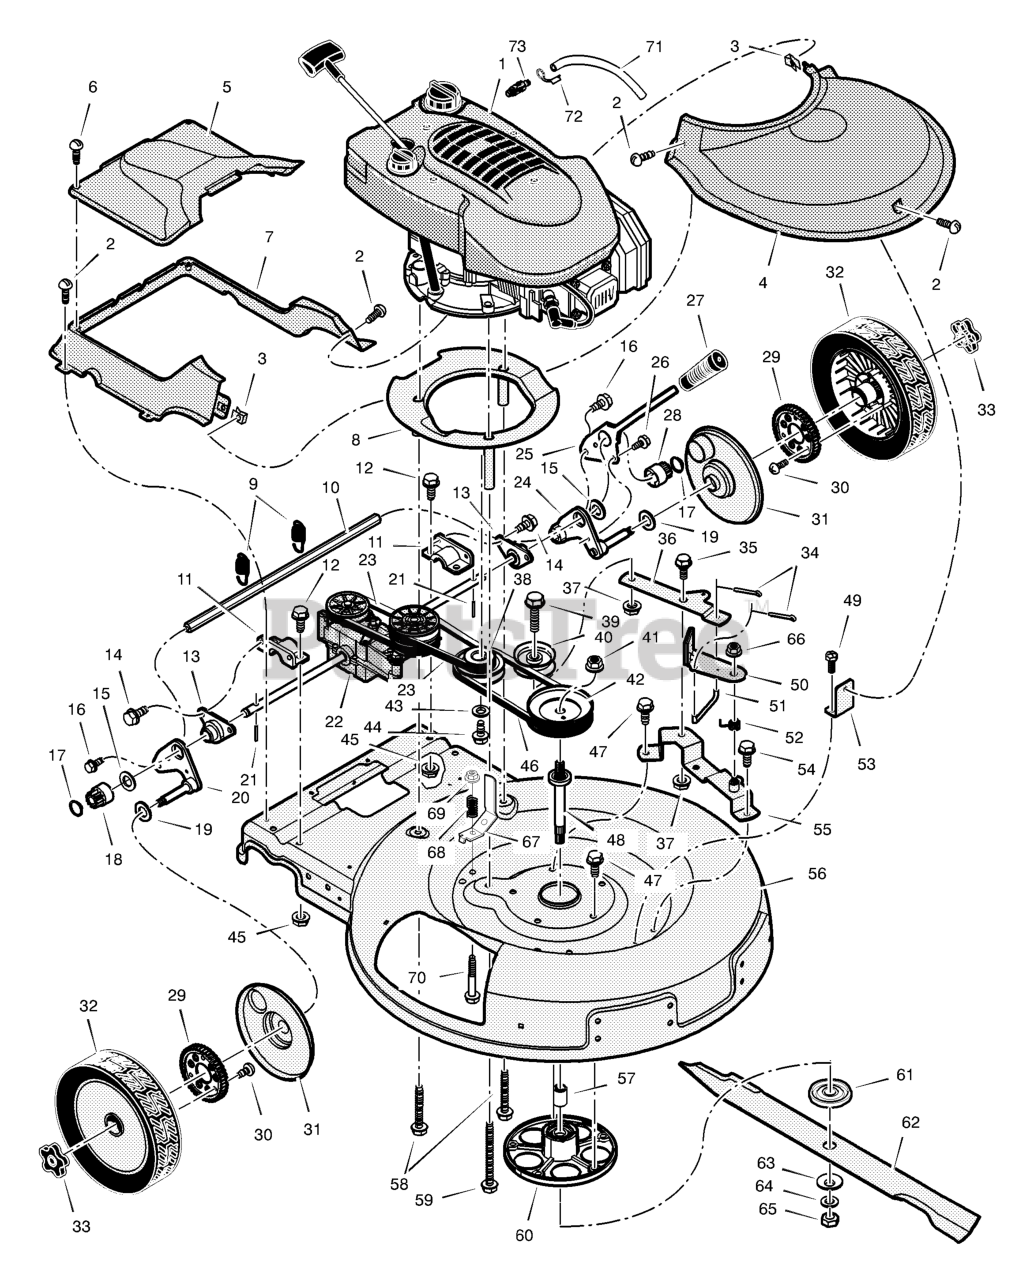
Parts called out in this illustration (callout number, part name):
1	Engine *
2	Screw
3	Tinnerman, "U"
4	Cover, Front
5	Cover, Transmission
7	Cover, Rear
8	Base Assembly, Engine
9	Spring, Extension
10	Crossbar, Rear
11	Bearing, Axle Support
12	Screw
13	Retainer Assembly, Axle Bearing
15	Washer, Thrust
17	Retainer Ring
18	Gear, Right Pinion
19	Washer, Spring
20	Bracket Assembly, Right Axle
21	Pin, Drive
22	Transmission
23	Belt, Transmission
24	Bracket Assembly, Left Axle
25	Lever, Spring Height Adjuster
26	Screw, Tap
27	Knob, Height Adjuster
28	Gear, Left Pinion
30	Screw, Tap
31	Cover, Dust
32	Wheel, Drive
33	Knob, Axle
34	Pin, Cotter
35	Bolt, Shoulder
36	Idler Arm
37	Nut, Flange
38	Pulley, Engine
39	Screw
40	Pulley, Idler
41	Nut, Blade Pulley
42	Pulley, Blade
43	Washer, Split
44	Screw
46	Belt, Blade Drive
47	Bolt
48	Jackshaft
50	Brake Assembly, Blade
51	Link, Blade Brake
52	Spring, Torsion
53	Bracket, Front Cover
55	Support Assembly, Idler & Brake
57	Spacer, Jackshaft
58	Bolt, Short Engine Mount
59	Bolt, Long Engine Mount
60	Mandrel Assembly
61	Adapter, Blade
63	Washer, Cup
64	Washer
65	Nut, Blade Mount
66	Nut
67	Guide, Belt
69	Nut
71	Tube, Oil Drain
72	Cap, Oil Drain
73	Valve, Oil Drain
